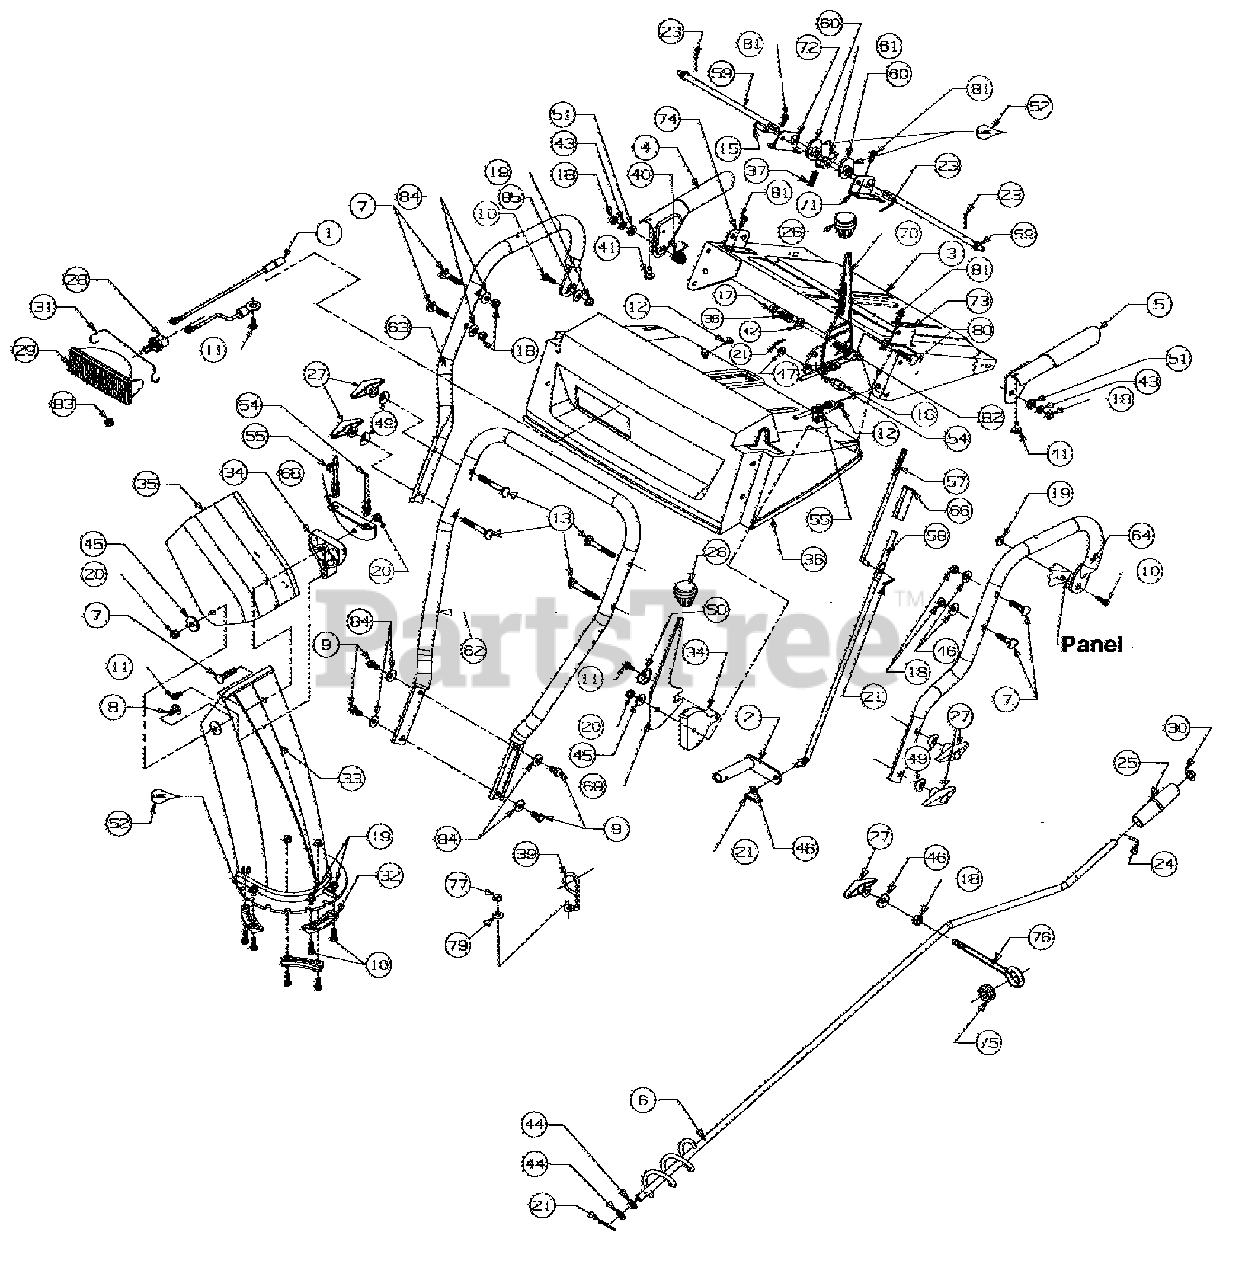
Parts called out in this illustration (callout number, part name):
1	Harness-Light
4	Handle-Engagement-R.H.
5	Handle-Engagement-L.H.
6	Crank-Chute
7	Bolt-Carriage
8	Bolt-Carriage
9	Screw-Hex
10	Screw-Hex
11	Screw-Washer Head-Hex
12	Screw-Hex
13	Bolt-Carriage
15	Pin-Clevis
16	Ferrule
17	Nut-Hex Lock
19	Nut-Hex Lock
20	Nut-Hex Lock
21	Pin-Cotter Internal
23	Pin-Cotter
24	Pin-Roll
25	Knob-Chute Crank
26	Knob-Shift
27	Knob-Wing Nut
28	Lamp
29	Housing-Lamp
31	Clip-Retaining
32	Keeper-Chute
33	Chute-Lower
34	Guide-Cable
35	Chute-Upper
36	Panel-Handle
39	Wire-Control
42	Washer-Bell
43	Washer-Lock
44	Washer-Flat
46	Washer-Bell
47	Washer-Flat
49	Washer-Saddle
50	Washer
52	Lubricant
54	Cable-Chute Control
55	Cable-Chute Control
57	Rod-Shift Upper
58	Rod-Shift Lower
60	Cam-Handle Lock
61	Pawl-Handle Lock
63	Handle-R.H.
75	Grommet Rubber
76	Eyebolt-Chute
77	Nut-Hex Lock
79	Washer-Flat
80	Screw-Hex
81	Screw-Tap Hex
83	Nut-Sems Hex
84	Washer-Bell
